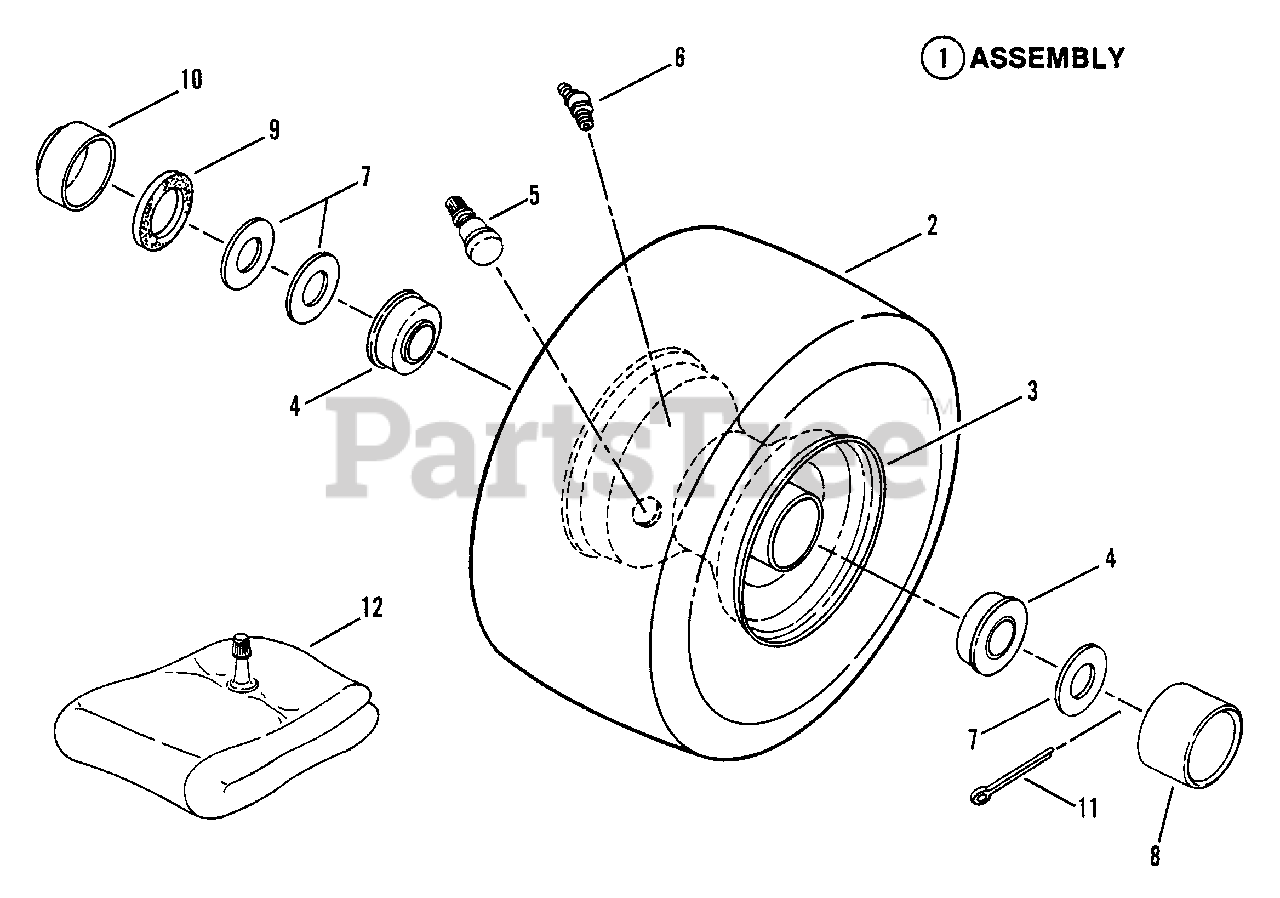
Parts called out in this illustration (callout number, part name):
1	ASSEMBLY, Front Tire & Rim (Complete)
2	TIRE, Pneumatic 4.10/3.50 x 4
3	RIM
4	BEARING, Ball
5	VALVE, Air (Snap-in)(8, 10 HP)
6	FITTING Lube
7	WASHER
8	CAP, Hub
9	SEAL, Felt
10	CAP, Dust
11	PIN, 5/32 x 1" Cotter
12	TUBE, Inner
